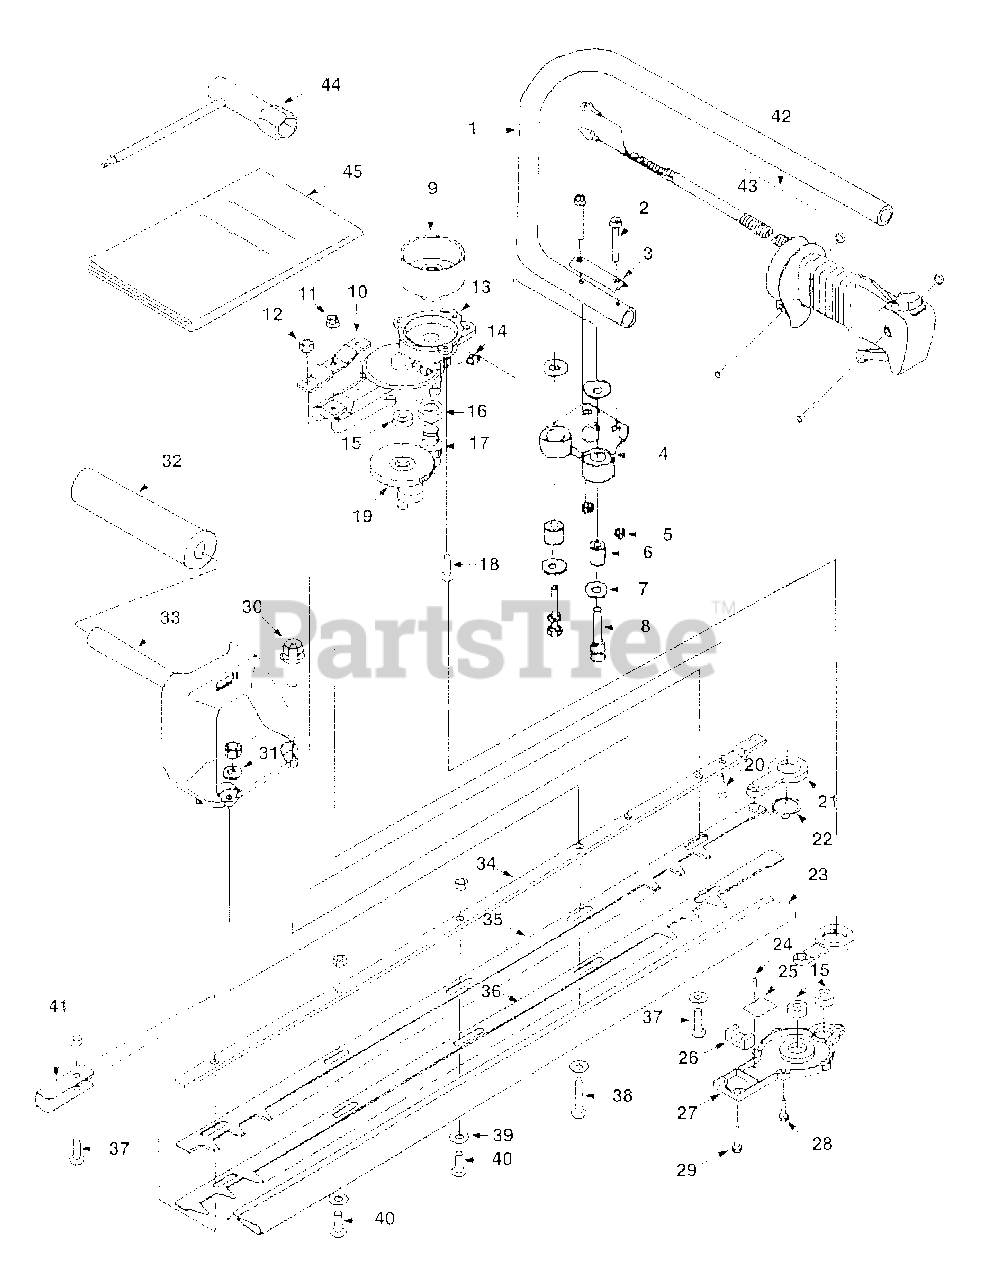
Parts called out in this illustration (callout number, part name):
2	Bolt; M5 x 30
3	Holder, Handle
4	Holder, Handle
8	Bolt; M6 x 26
9	Drum, Clutch
13	Case, Gear
14	Grease Nipples
15	Ball Bearing; 608Z
16	Ball Bearing; 6001
17	Gear, Pinion
18	Screw; M6 x 14
19	Gear, Crank
20	Screw; M5 x 20
22	Snap Ring
23	Cover, Blade
24	Screw; M3 x 5
27	Case, Gear
28	Bolt; M5 x 16
29	Bolt; M5 x 20
30	Bolt; M6 x 18
42	Lever Assembly, Throttle
43	Wire, Throttle
44	Spanner, Box
45	Instruction Book
